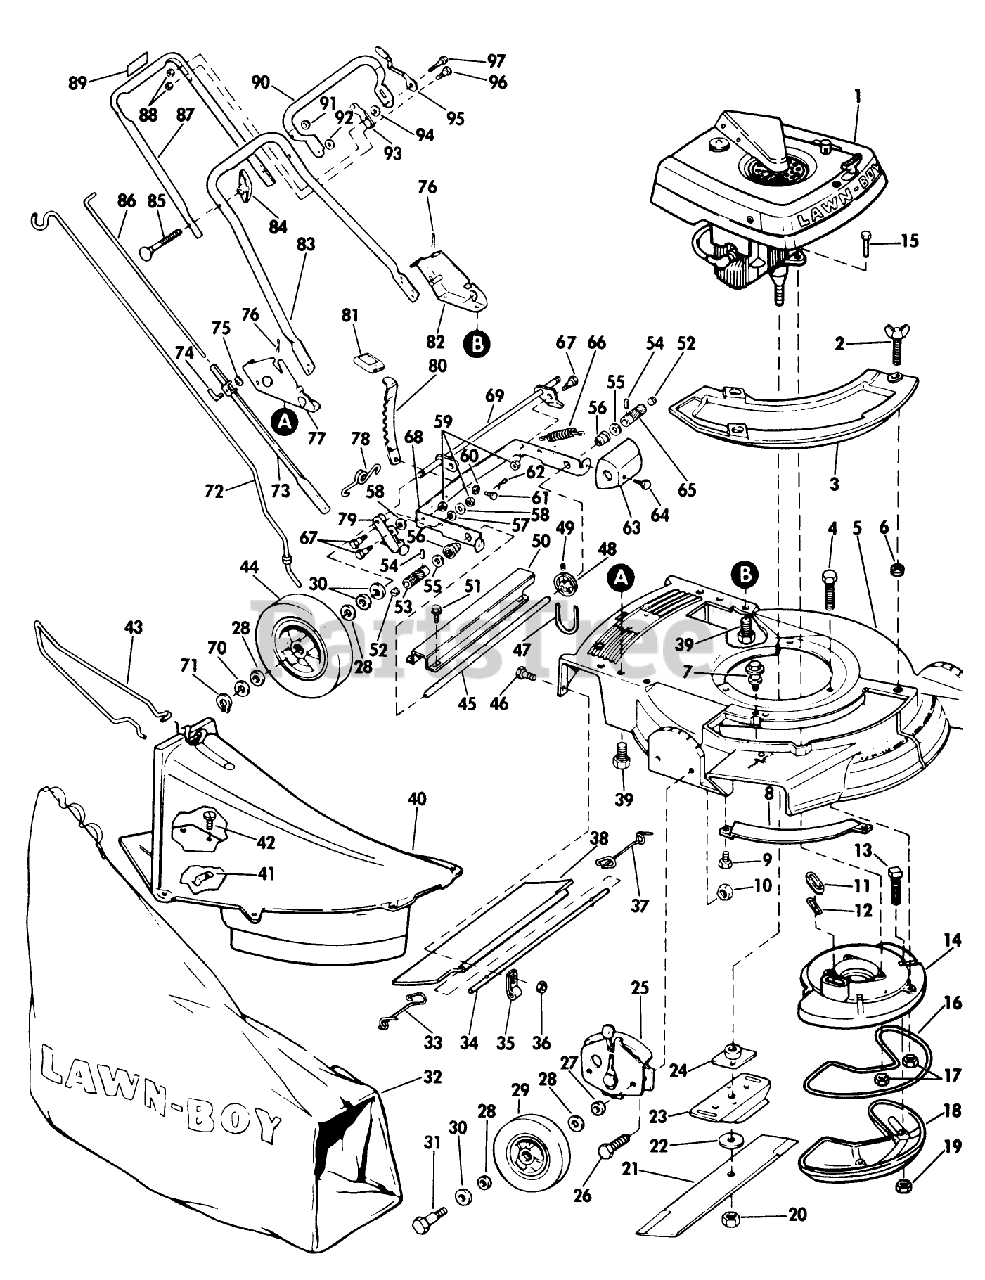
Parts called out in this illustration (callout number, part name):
2	WING SCREW LAWRE
4	SCREW
8	BAR-TOE
10	NUT
11	SLEEVE
12	GASKET S
17	NUT-LOCK F
20	NUT-BLADE
22	WASHER
24	PLATE AND COLLAR ASM
27	WASHER WROUGHT
28	WASHER
30	SPACER
31	BOLT WHEEL
32	89802 LB WHOLE GOODS
33	SPRING;TRAILING SHIELD RH
34	ROD 21" ADVANCE
35	CLAMP ROD KMC
37	SPRIG T/SHLD ASOC
39	SCREW
51	SCREW F
52	GREASE PLUG
54	PIN
58	WASHER S
59	STOP NUT
60	WASHER SPRING LAR
61	PIN
63	GUARD
66	SPRING
67	BOLT RB&W
70	SPACER
71	RET RING
72	ROD GRASSBAG
76	HAIR PIN
78	SPRING N.A.S
80	LEVER
81	KNOB
83	Cover Plate
85	SCREW
86	ROD CONTROL
92	WASHER M
95	KNOB & SPRING
97	BOLT RB&W
